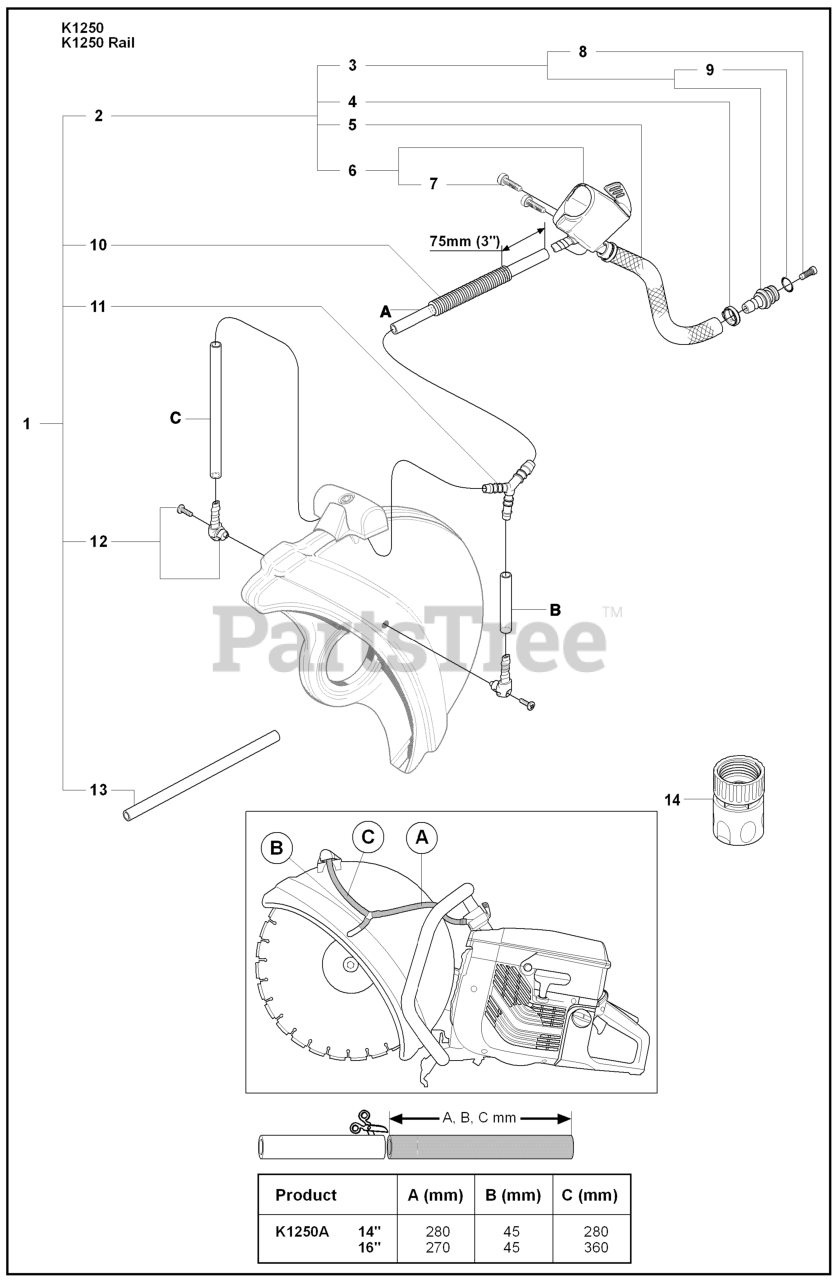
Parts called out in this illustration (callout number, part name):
1	WATER HOSE KIT
2	HOSE
3	NIPPLE
4	CLAMP
5	%HOSE
6	VALVE COMPLETE
7	SCREW
8	FILTER
9	RP O-RING
13	RP HOSE 800MM
14	FEMALE QUICK COUPLER
